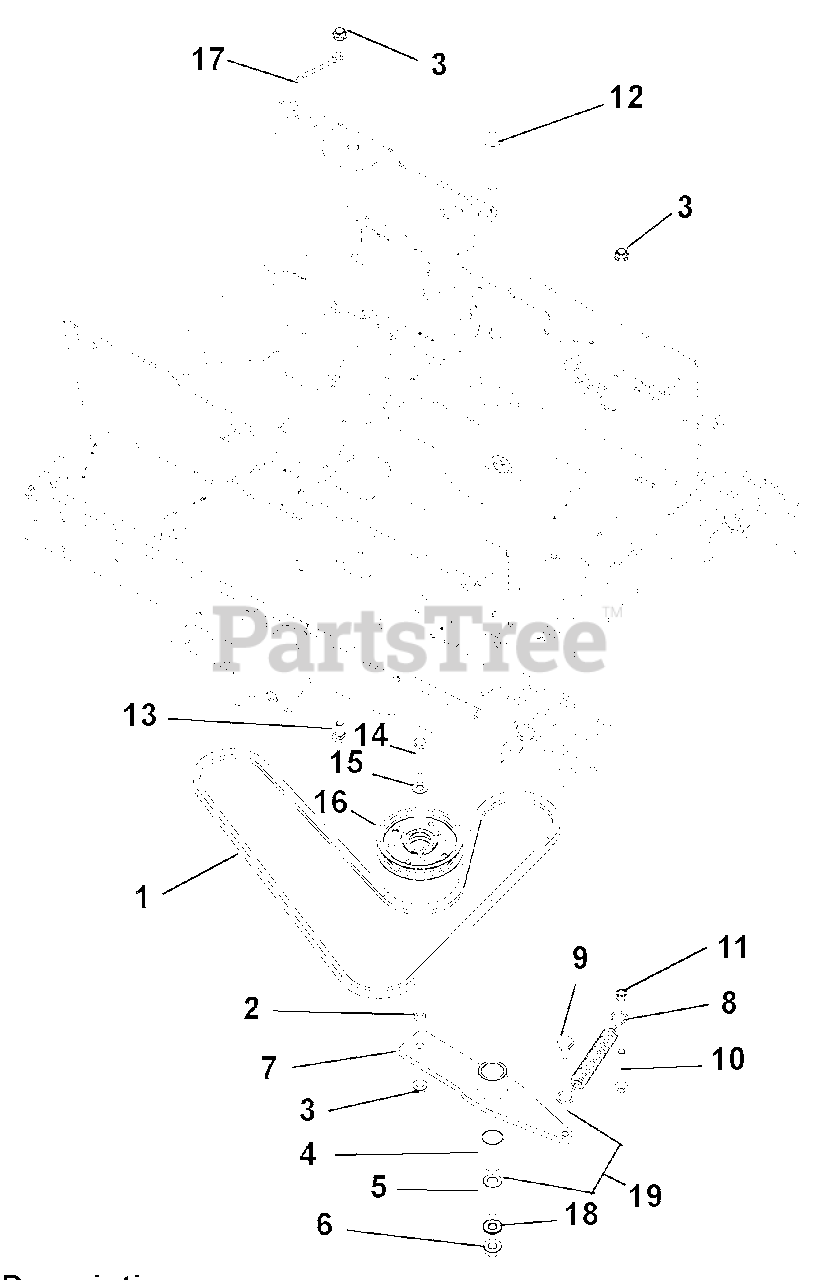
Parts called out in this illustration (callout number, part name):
1	V-BELT, 4L-WRAPPED
2	WSHR-FL-STL .406X1.375X.135 YZ
3	@NUT-LK-NYL-FLG .38-16 YWZC
4	BSHG, 1.00 X 1.125 X 1.937
5	BSHG, SPCR .502X.997X2.03 PM
6	@NUT-LK-NYL-FLG .50-13 YWZC
7	HYDRO DRIVE IDLER ARM WMT -BLK
8	SPRING, EXTENSION
9	BLT,SHLDR EP .38-16X.30 HEX YZ
10	@BLT-HEX .38-16X2.50 GR5 YWZC
11	@NUT-HEX .38-16 YWZC
12	@BLT-HEX .50-13X3.25 GR5 YWZC
13	@BLT-RDHDSQNK .38-16X1.00 G5YZ
14	@BLT-HEX .38-16X2.00 GR5 YWZC
15	@WSHR-FL-STL.406X.812X.065 YWZ
16	ASM, 4" IDLER (.75 WIDE)
17	BELT FINGER
18	WSHR-FL-STL.511X1.441X.125 YWZ
19	ASM, IDLER PIVOT ARM (HYDRO)
